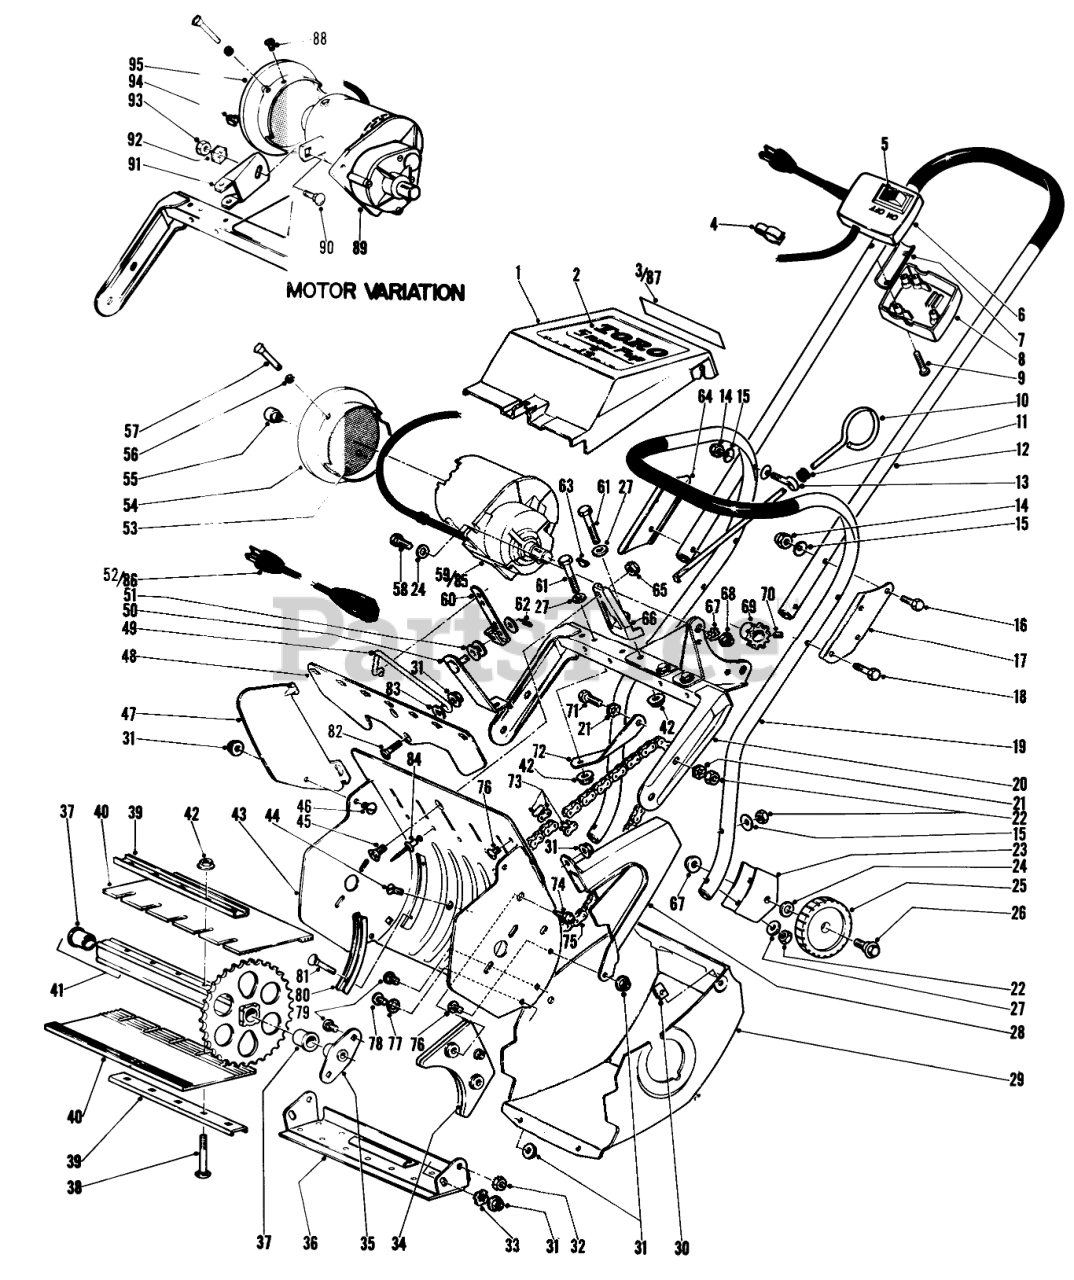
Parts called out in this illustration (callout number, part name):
1	Shroud, Upper
2	Decal
3	Decal
5	Switch-Single Throw
6	Switch Housing, Upper
7	Insert, Switch Housing
8	Switch Housing, Lower
10	Vane Adj. Rod
11	GROMMET
12	Handle, Upper
13	Bolt-Eye
14	NUT-CAP
15	WASHER
17	SPLICE PLATE
19	Handle, Lower
20	Frame Assembly
21	Washer
22	Nut
23	Bracket Wheel
24	WASHER-PLAIN
25	Wheel
26	Bolt-Shoulder
27	WASHER-FLAT
28	Chain Guard
29	Lower Shroud
30	NUT-SPEED
31	NUT-LOCK, FLANGE
32	NUT-KEPS
33	Washer
34	Stripper
35	Rotor Shaft Assy.
36	Skid, Riveted Assy.
37	Bushing
39	Reinforcing Strap
40	Blade-Rotor
41	Sprocket & Tube W.A. Incl. #37
42	Nut
43	Housing
45	5/16-18X5/8 FLT HD MS
46	SCREW-PTH
47	Vane
48	Mount Vane
49	Linkage Vane Adj.
50	Vane Adj. Bracket
51	WASHER-FLAT
52	100 Ft. Cord
53	Filter Assy.
54	Housing Filter
55	Spacer
56	Grommet
57	Oiler
58	SCREW-HH
59	Motor
60	Bracket-Vane Adj.
61	SCREW-HH
62	PIN-COTTER
64	Plate-Splice
65	NUT-LOCK, NI
66	Stiffener
67	Lockwasher
68	NUT-HHF
69	SPROCKET
70	SCREW-SET, HSH
71	SCREW-HH
72	Bracket
73	LINK-CONNECTING, NO. 35
74	Screw
75	CHAIN
76	SCREW-PTH
77	Washer
78	SCREW-HEAD, PAN
79	SCREW-CARRIAGE
80	Handle Plate
81	SCREW-CARR
82	10-24X1-1/8 FLT HD MS
83	WASHER-FLAT
84	RIVET
85	Motor
86	Cord-100 Ft.
87	Decal
88	Screw
89	Motor
90	BOLT-CARR
91	Bracket Rear
92	WASHER-LOCK
93	NUT-HEX
94	Clip Tinnerman
95	Housing
